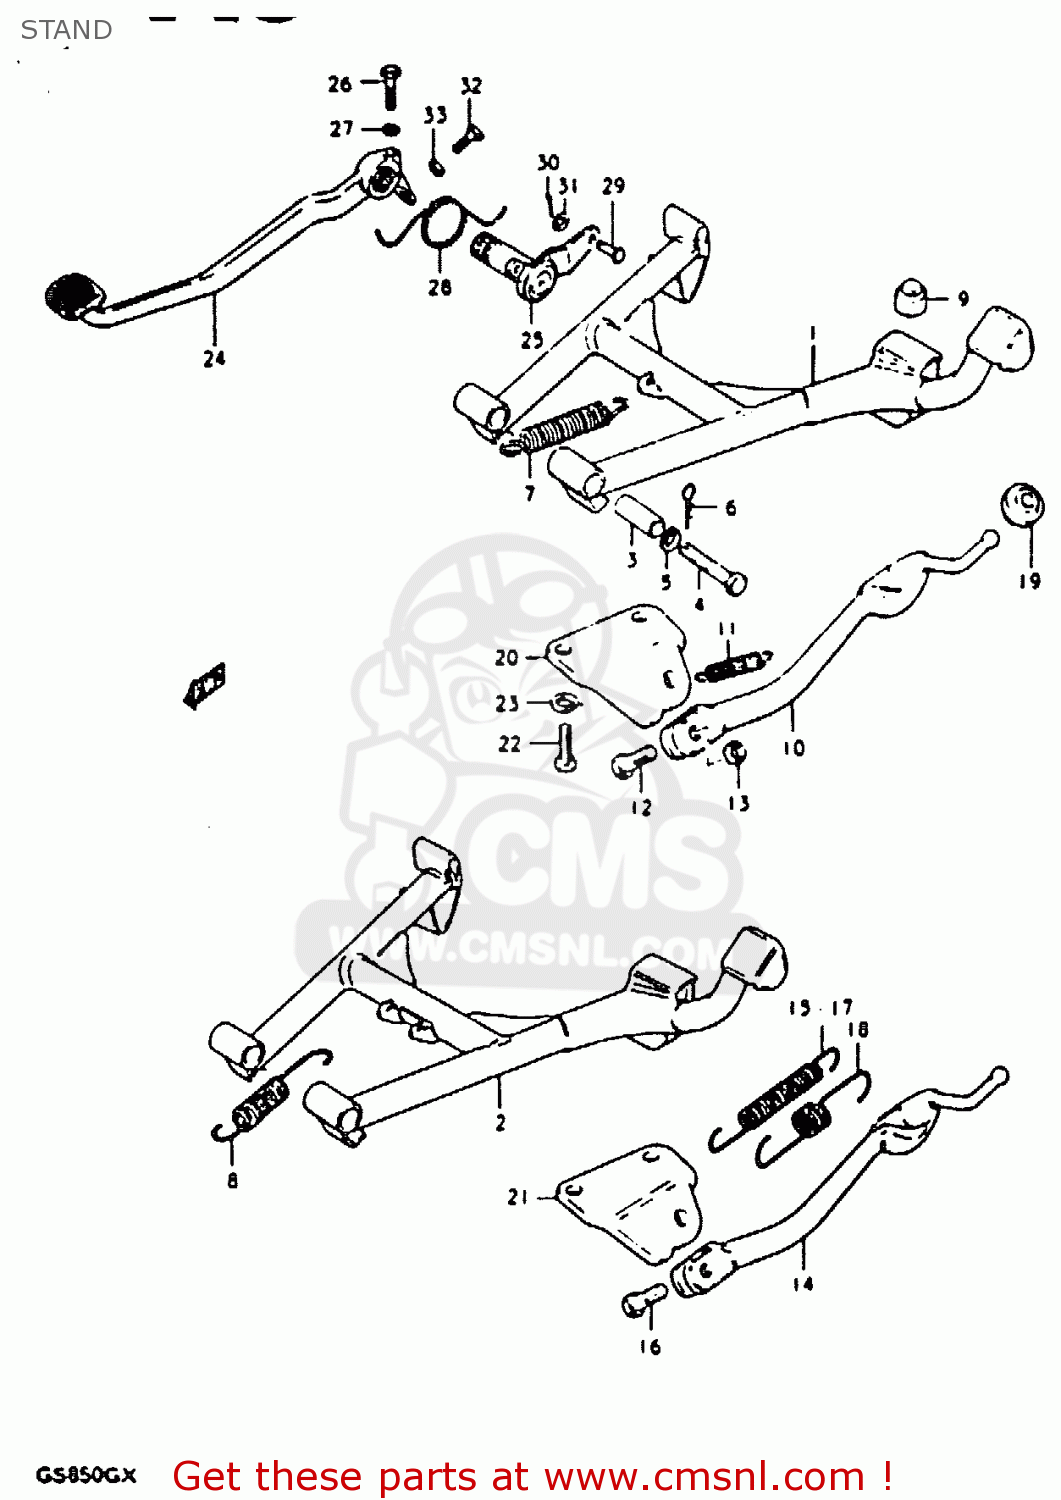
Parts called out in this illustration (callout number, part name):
1	STAND,CENTER
3	SPACER(10X16X38.8)
4	BOLT
5	LOCK WASHER
6	CLIP
7	SPRING
9	CUSHION
10	STAND,PROP
11	SPRING
12	BOLT(10X30)
13	NUT
19	CUSHION
20	BRACKET,SIDE STAND
22	BOLT
23	LOCK WASHER
24	PEDAL,BRAKE
25	ARM,BRAKE PEDAL
26	BOLT
27	LOCK WASHER
28	SPRING
29	PIN
30	PIN
31	WASHER
32	BOLT
33	NUT
